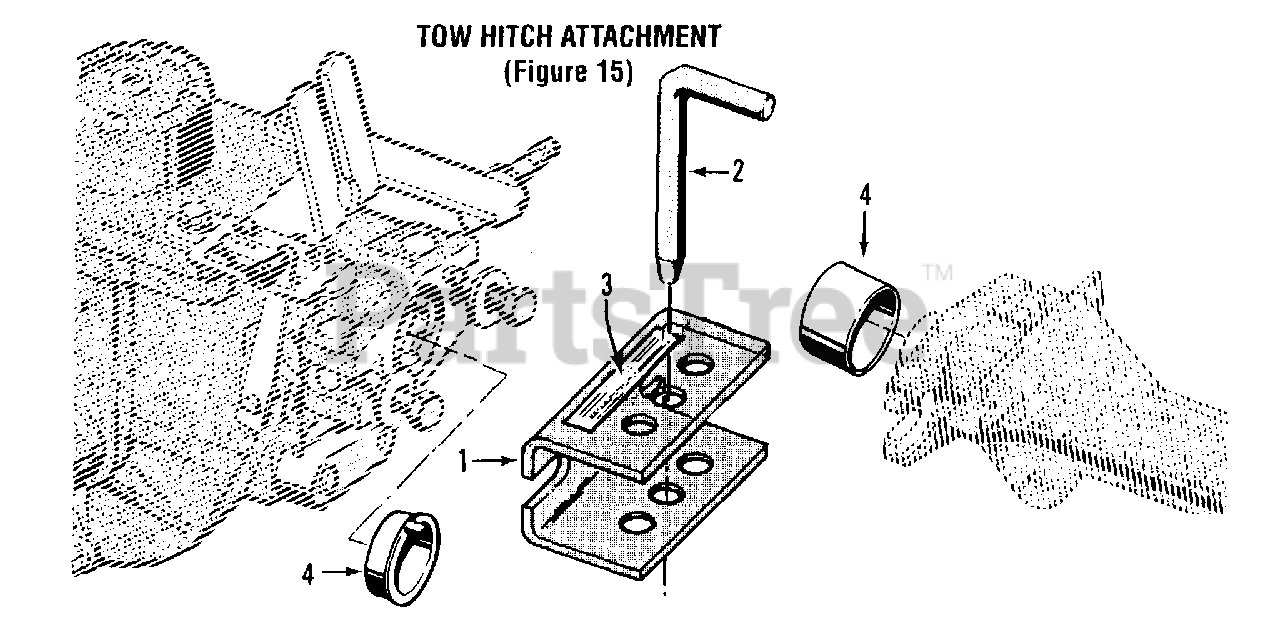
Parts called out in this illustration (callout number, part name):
1	Hitch-mounting plate
2	Pin-hitch
3	Decal-warning instructions
4	Dust Caps-2 protective covers
